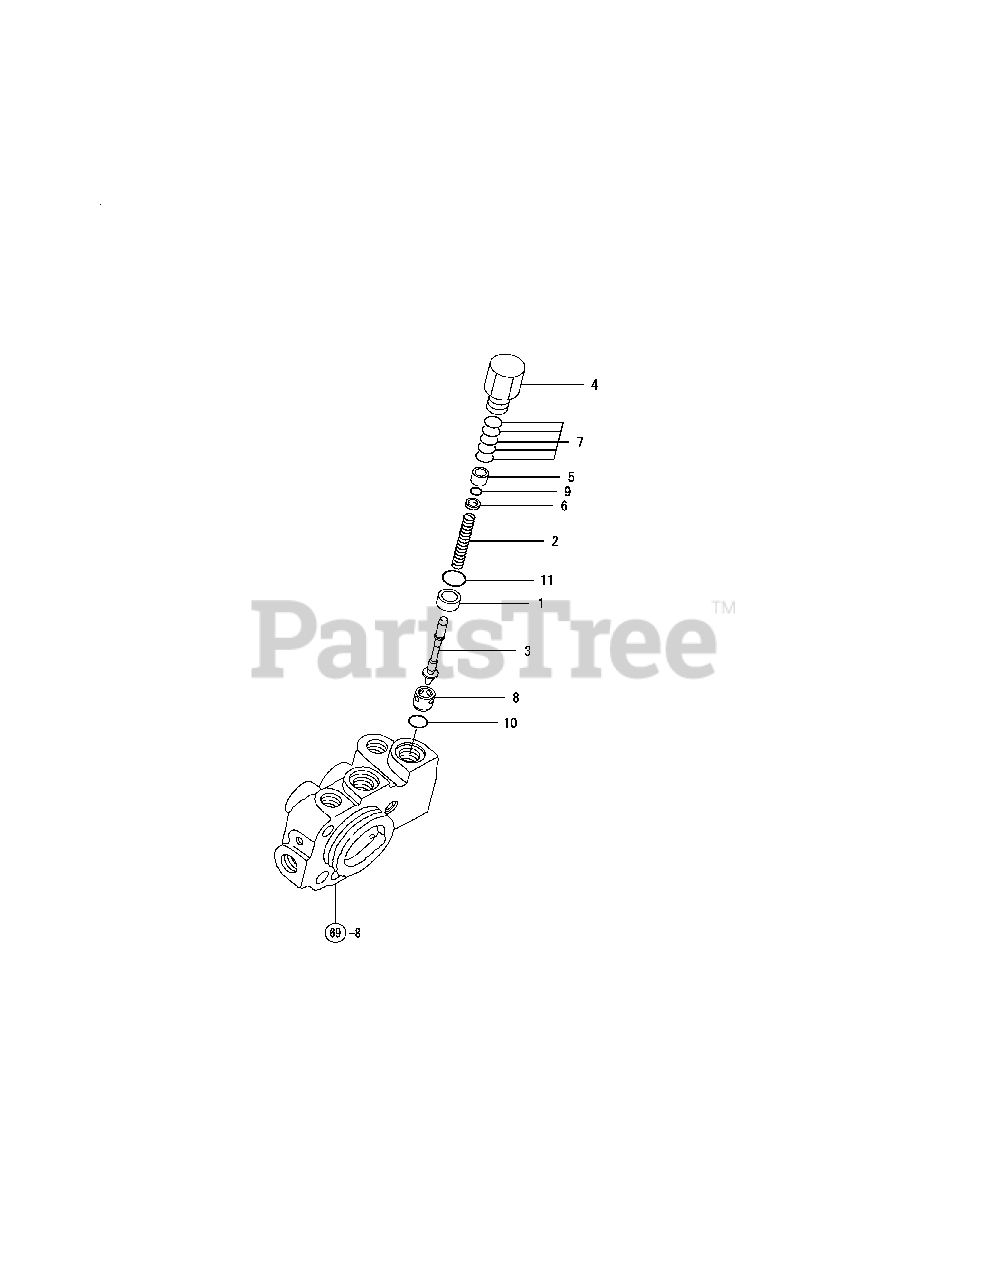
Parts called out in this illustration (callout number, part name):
1	COLLAR, VALVE SEAT
2	SPRING, RELIEF VALVE
4	PLUG, RELIEF VALVE
8	SEAT, RELIEF VALVE
10	O-RING 1A P 12.0
11	O-RING 1A P-18.0
